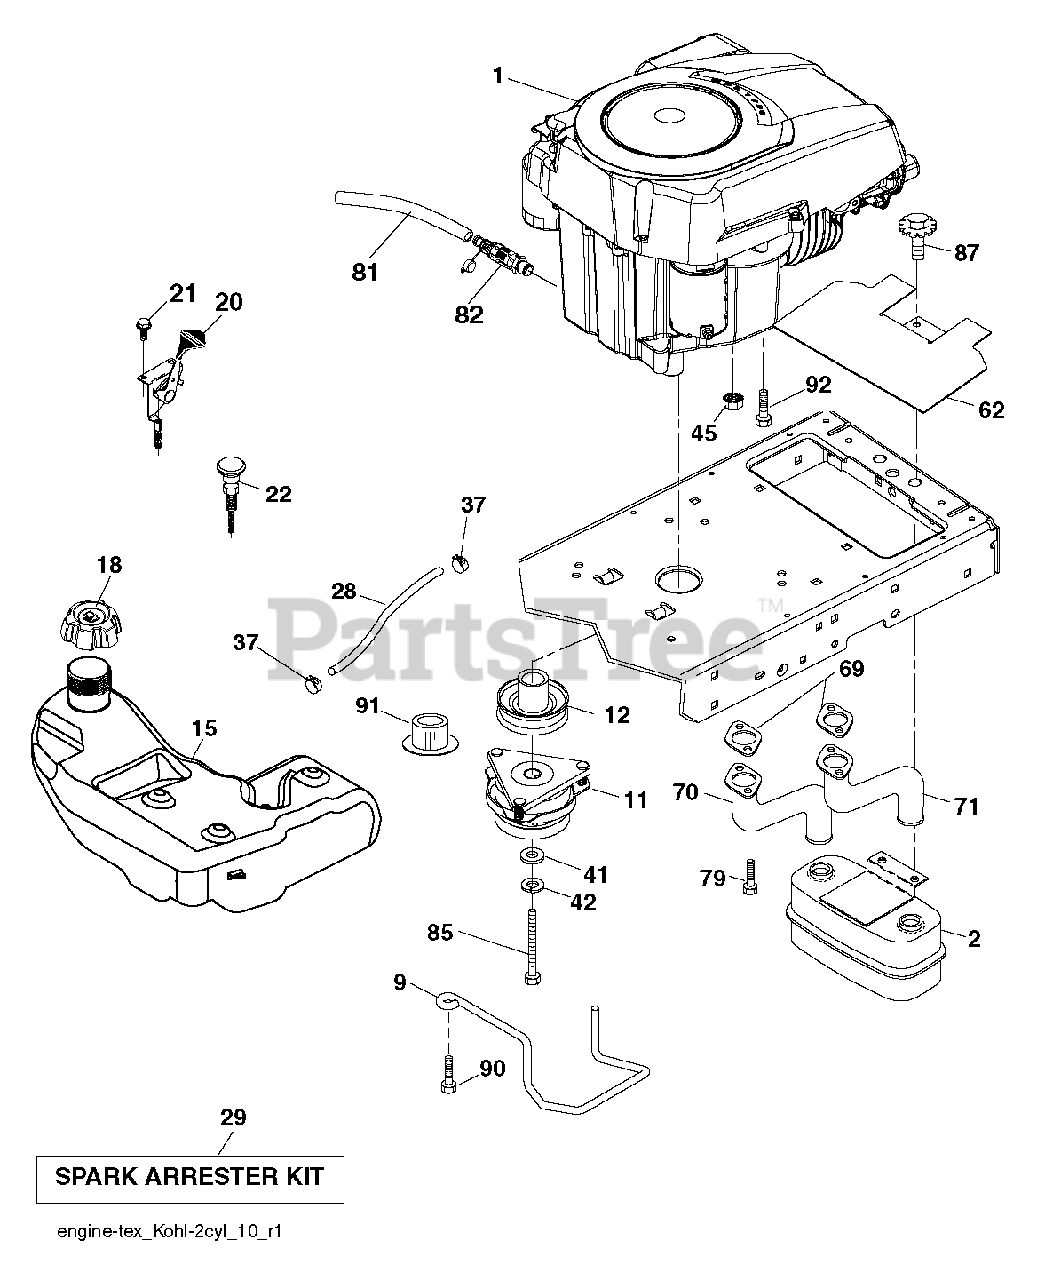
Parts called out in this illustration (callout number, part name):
2	MUFFLER.ASM.TWN.EXTNDED.DFLCTR
9	KEEPER.BELT.ENGINE.4.2
11	CLUTCH.ELECTRIC.LT.48"*
12	PULLEY.ENGINE.TUFFTORQ
15	TANK.ASSY.3.GAL.EPA
18	CAP.ASM.FL.RITCH.3"E10.SYM.498
20	THROTTLE CONTROL
21	SCREW.#10 X 0.750.BOS
22	CONTROL.CHOKE.ERGO.PUSH-IN.BLA
28	LINE.FUEL.64"REAR.EMIS
29	KIT.SPARK ARRESTOR 794945 B&S
37	HOSE CLAMP
42	LOCKWASHER
45	NUT
62	SHIELD.HEAT.MUFFLER
69	GASKET.EXHAUST.KOHL.CV18-CV26
70	RP.PIPE-EXHAUST LH
71	RP.PIPE-EXHAUST RH
79	SCREW.SOCKET HD.5/16-1
81	TUBE, DRAIN OIL ASM.
82	VALUE.OIL.DRAIN
85	BOLT HEX 7/16-20X4-1/4"
87	BOLT, 5/16-18 X 1 3/4
90	SCREW 3/8-16X1
91	BUSHING.1.375OD
92	SCREW 3/8-16X1
